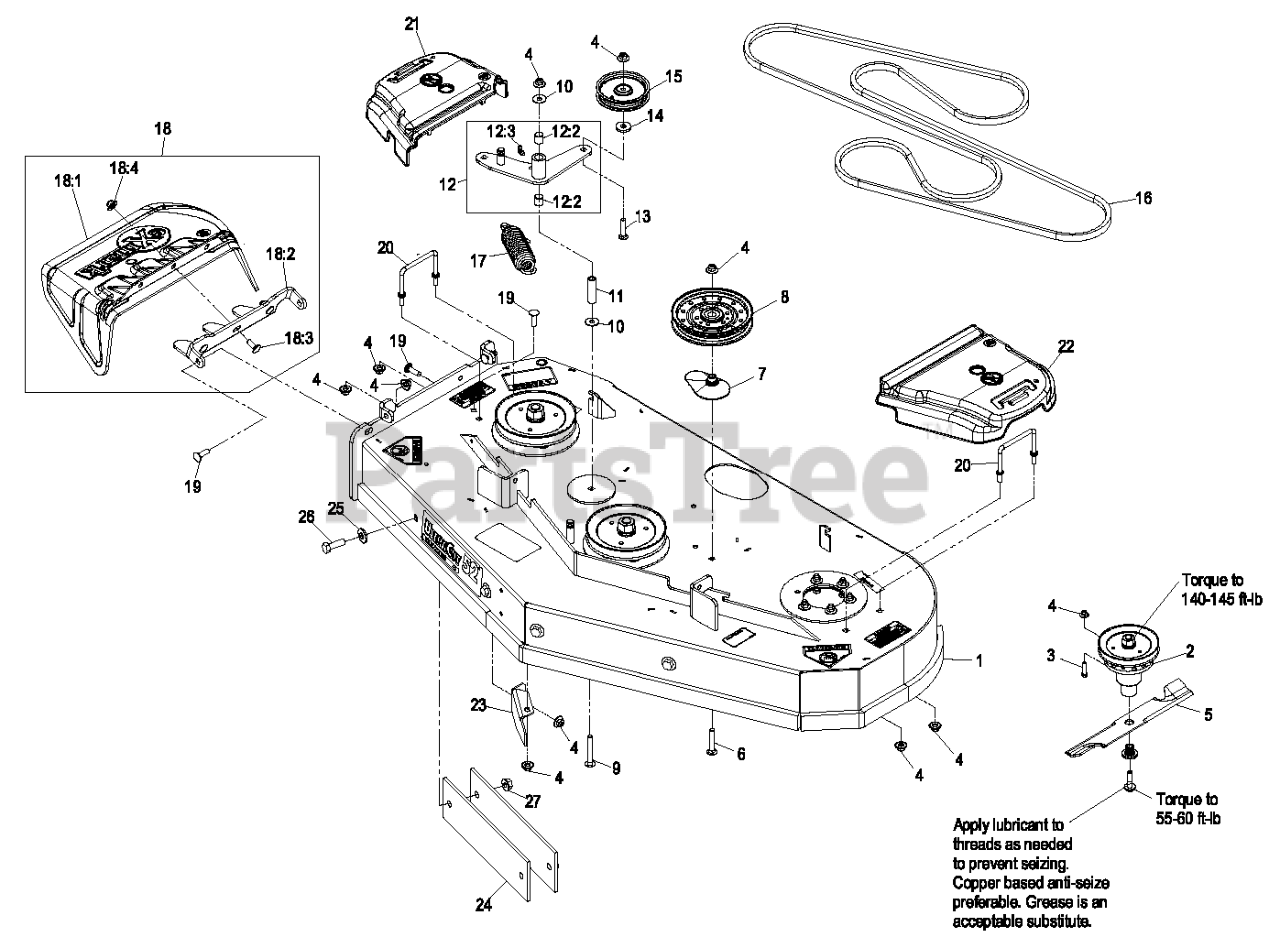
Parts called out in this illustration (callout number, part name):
1	DECK ASM, 524
2	ASM, CUTTER HOUSING 52
3	SCREW-HH
4	Nut-Nyloc 3/8-16 Flg
6	Bolt-Carriage 3/8-16 X 2 1/4
7	SPACER-PULLEY
9	SCREW-CARR
11	BUSHING-PIVOT, IDLER
12	IDLER ASM
12:2	SLEEVE-BEARING
12:3	FITTING-GREASE, 90 DEG
13	SCREW-CARR SPECIAL
15	PULLEY-IDLER
16	BELT-V
18	ASM,DISCHARGE CHUTE
18:1	CHUTE,DISCHARGE
18:2	BRACKET,DISCHARGE CHUTE
18:3	SCREW-CARR
18:4	Nut-Nyloc 3/8-16 Flg
19	Bolt-Carriage 3/8-16 X 1 1/4
20	WIREFORM-COVER
21	COVER-BELT, RH
22	COVER-BELT, LH
23	BAFFLE,DISCHARGE 52/60
24	BAR,WEIGHT
25	WASHER-SPRING
26	SCREW-HH
27	NUT-HHF
